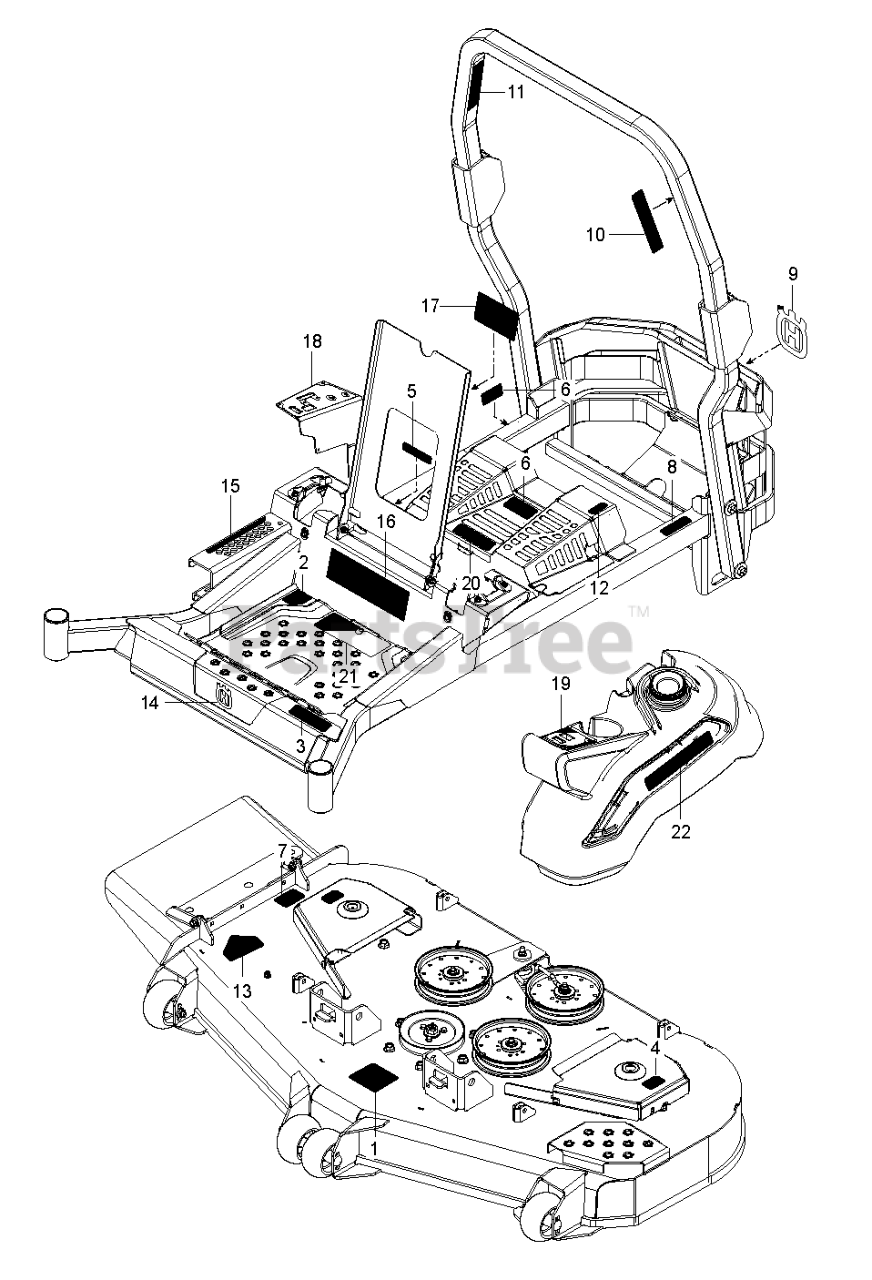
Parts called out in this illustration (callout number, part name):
1	DECAL, BELT ROUTING
1	DECAL, 72" BELT ROUTING
2	DECAL.ZTR.SADLE.WARN.PZ500.ENG
3	DECAL.ZTR.PZ500SERIES.Z554X
4	DECAL.DECK.6MIL.EURO.NOSTEP
5	EURO DECAL-BATTERY WARNIN6
6	DECAL, BELT DRIVE
7	DECAL.DECK.6MIL./DEF.SHLD.WARN
8	DECAL, WARNING SPARK ARRESTOR
9	DECAL, CROWN H, 110MM
10	DECAL ROPS DECAL DECAL.ROPS.PZ
11	DECAL, ROPS, WARNING
12	DECAL, FUSE
13	DECAL, DECK DEFLECTOR, WARNING
14	DECAL.BADGE.55MM.CROWNH.HUSQ
15	DECAL.PZ500.DECKLIFT.HUSQ
16	DECAL.ZTR.SADDLE.COMM.PZ500
17	DECAL.PZ500.MAINTANCE/SVC.2018
18	DECALZTR.CONTROLPANEL.PZ500.RH
19	DECAL.ZTR.CONTROLPANL.PZ500.LH
20	DECAL.ZTR.TRANCOVER.WARN.PZ500
21	DECAL.ZTR.SADLE.WARN.PZ500.ENG
22	DECAL.HUSQVARNA.210MM
